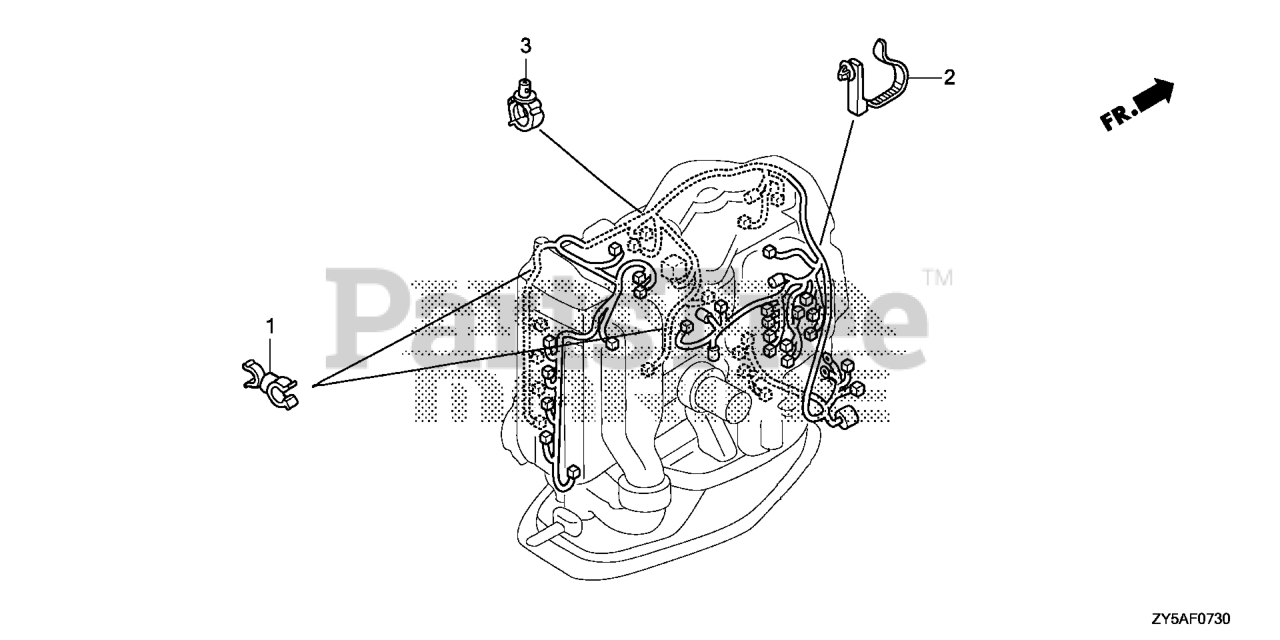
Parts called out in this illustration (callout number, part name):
1	CLAMP, HOSE
2	BAND, HARNESS OFFSET (10) (122.5MM) (BROWN)
3	CLAMP, ENGINE SUB-WIRE
